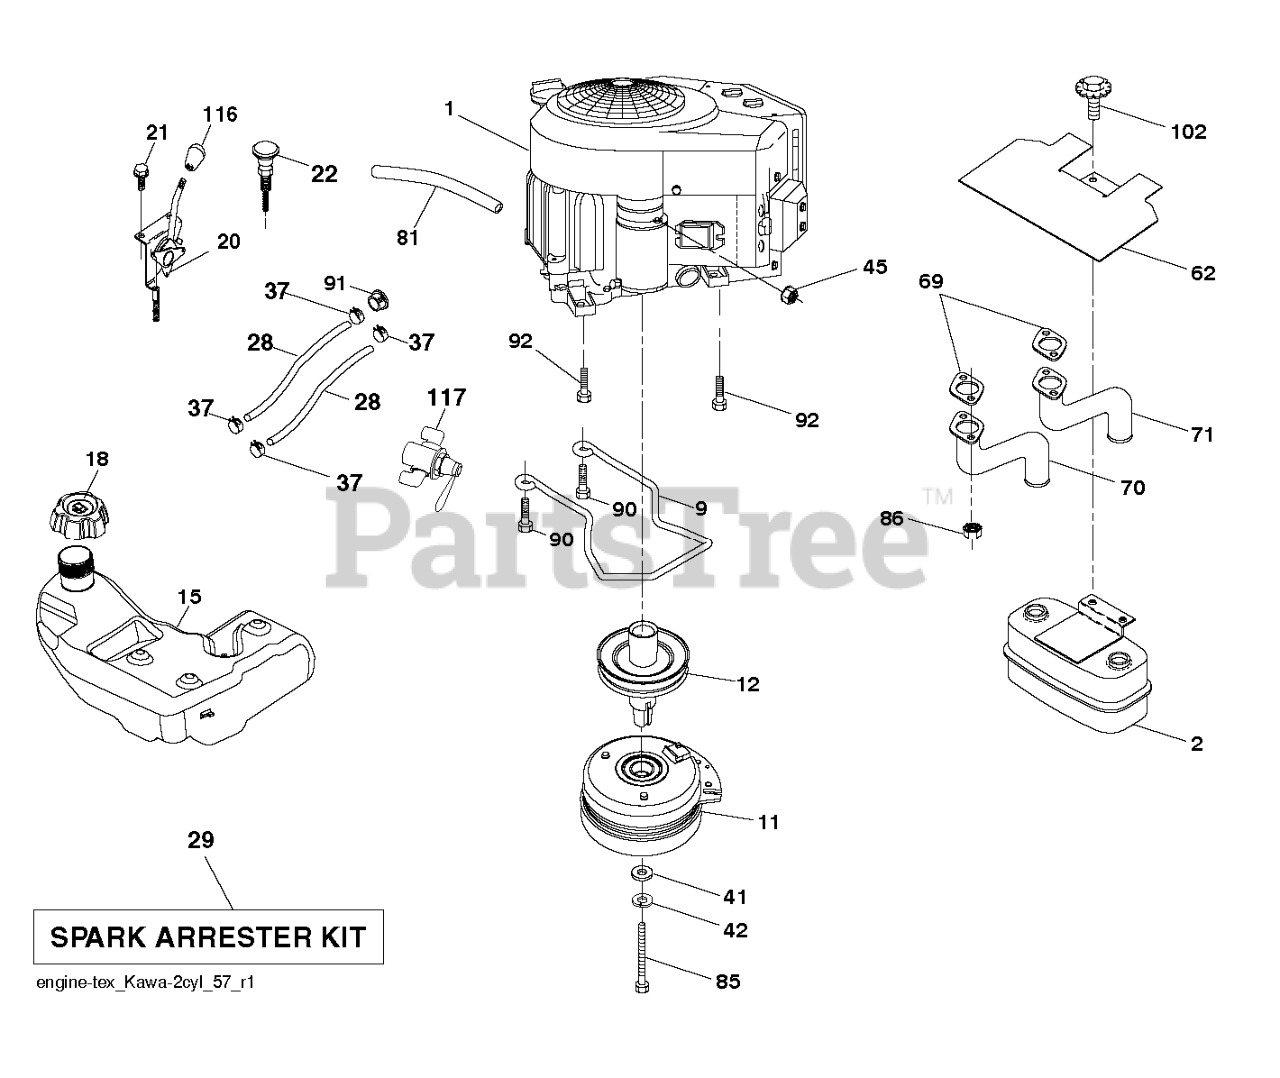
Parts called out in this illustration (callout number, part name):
2	MUFFLER.ASM.TWIN.MNTG.BRACKET
9	KEEPER.BELT.ENG.4.25"2.BLT.431
11	CLUTCH. 5.0 PD. 2.5 OFFSET
12	PULLEY.EXTENDED.SHAFT.GROUND
15	TANK.ASM.FUEL.4R.GAL.EPA.18
18	CAP ASSY FUEL 3" GRAY
20	CONTROL.THROTTLE.PRO.
21	SCREW.#10 X 0.750.BOS
22	CONTROL, CHOKE
28	LINE.FUEL.64"REAR.EMIS
29	KIT.SPARK ARRESTOR 794945 B&S
37	HOSE CLAMP
42	WASHER 7/16 LOCK
45	NUT
62	SHIELD.HEAT.MUFFLER
70	TUBE.EXHAUST.LH.FR961/FR730
71	TUBE.EXHAUST.RH.FR961/FR730
81	TUBE, DRAIN OIL ASM.
85	BOLT.HEX.7/16-20X5.GR5.GREEN
86	NUT.HEX.FLANGE.TOPLOCK
90	SCREW 3/8-16X1
91	BUSHING.1.375OD
92	SCREW 3/8-16X1
102	SCREW
116	KNOB - SHIFT
117	VALVE FUEL RESERVE
